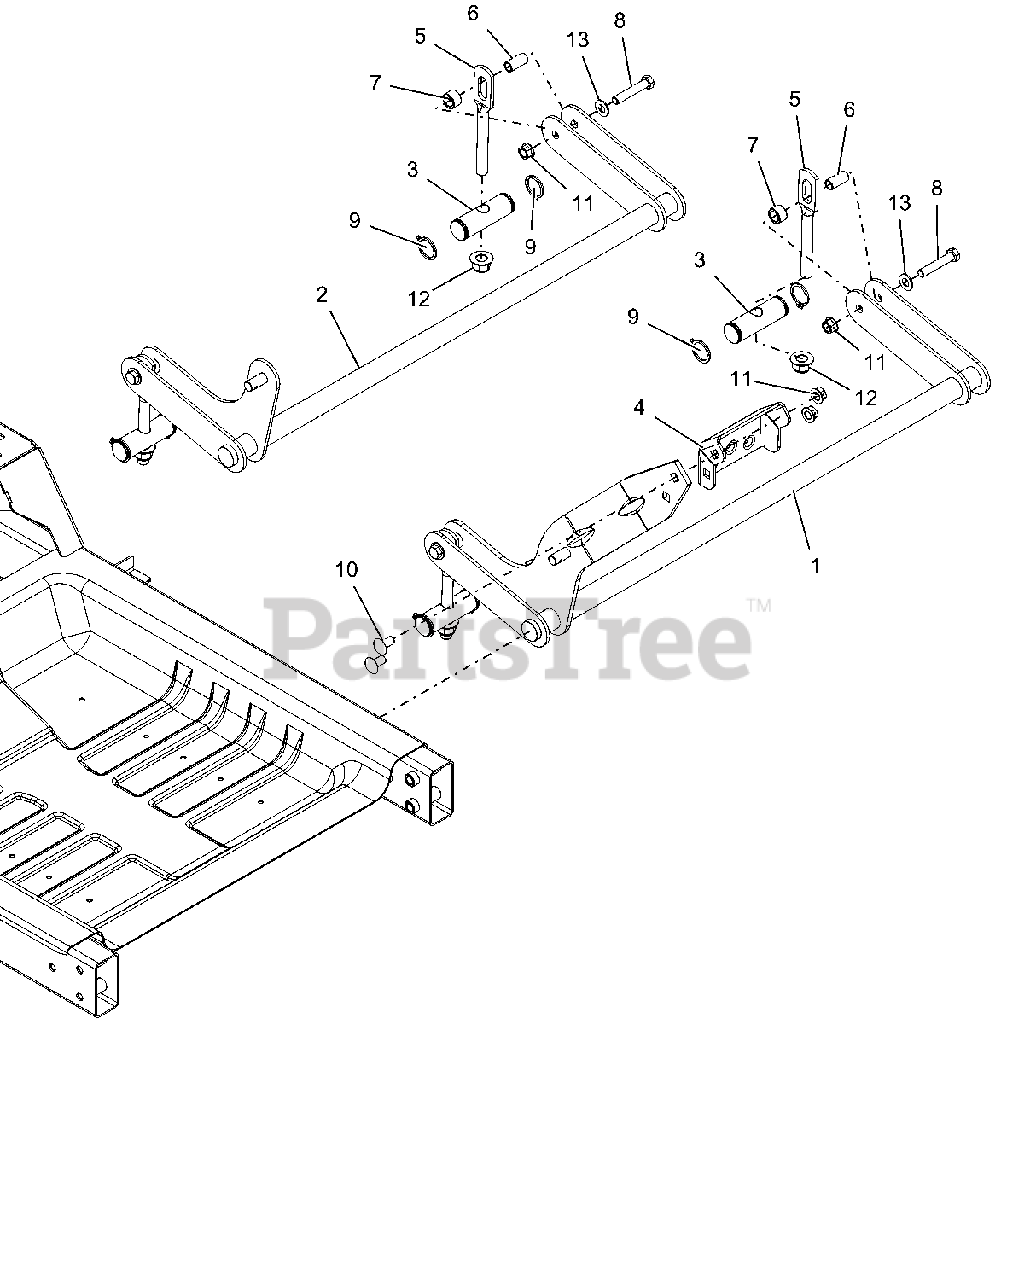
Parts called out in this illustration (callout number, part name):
1	WLDMT, FRONT DECK LIFT PIVOT
2	WLDMT, REAR DECK LIFT PIVOT
3	SHAFT, DECK LINK PIVOT
4	PEDAL, DECK LIFT (BOLT ON)-BLACK
5	LINK, DECK (LONG)
6	BSHG, SLV .385 X .500 X 1.045
7	BSHG, SLV .510 X .751 X .475
8	BLT-HEX .38-16X2.00 GR8 YWZC
9	RG-RTNG-EXT 1.00X.078
10	BLT-RHDSSQNK .38-16X.75 RIE5230
11	NUT, LK-CTR-FLG .38-16 YWZC
12	NUT-LK-NYL-FLG .50-13 YWZC
13	WSHR-FL-STL.406X.812X.065 YWZ
